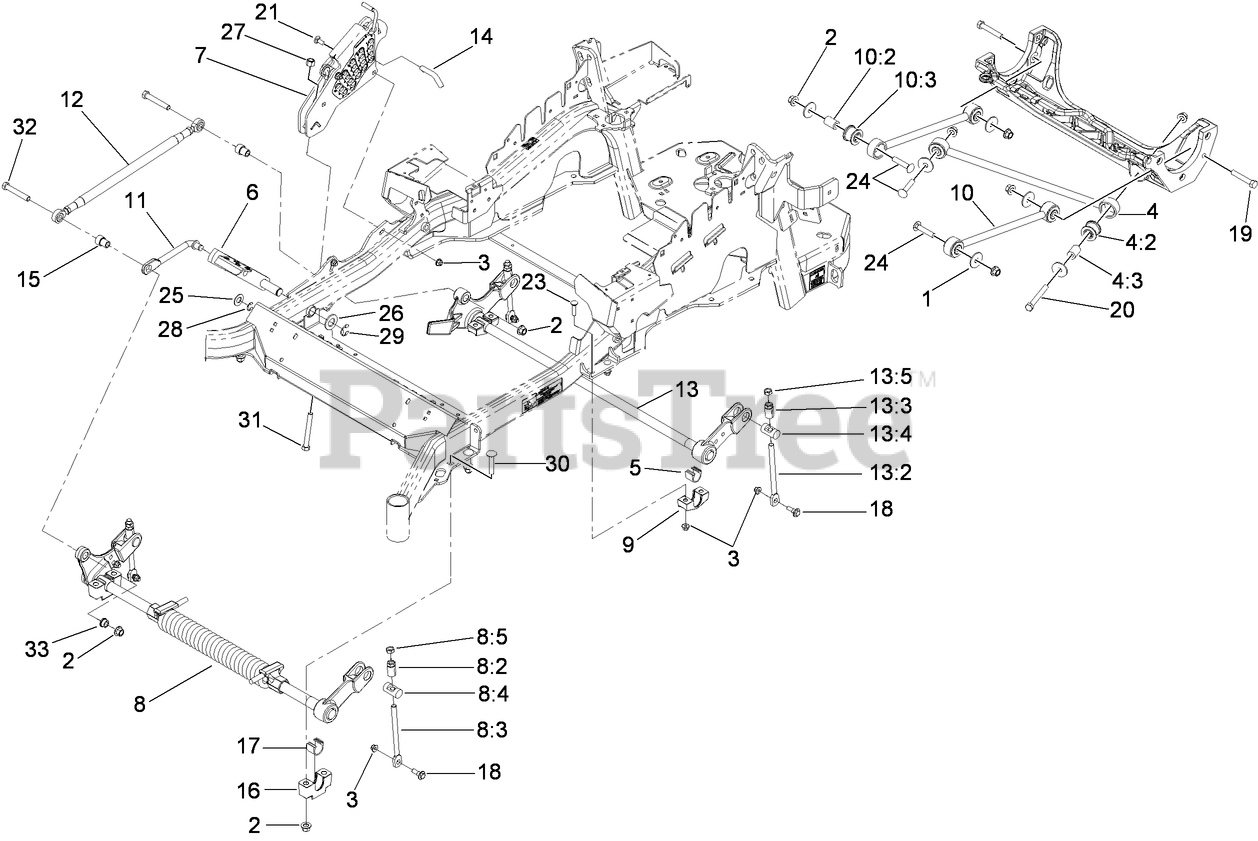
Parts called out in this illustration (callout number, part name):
1	WASHER-THRUST
2	NUT-LOCK
3	NUT-HF, NI
4	PANHARD ROD ASM
4:2	BUSHING-SUSPENSION, RUBBER
4:3	SPACER
5	BEARING-CROSS SHAFT, REAR
6	LEVER-FOOT
7	HOC ASM
8	FRONT CROSS SHAFT ASM
8:2	ADJUSTER-LIFT, DECK
8:3	LINK-ADJUSTER, DECK LIFT
8:4	TRUNNION
8:5	NUT-JAM
9	SUPPORT-CROSS SHAFT, REAR BEARING
10	DECK STRUT ASM
10:2	BUSHING-SUSPENSION, RUBBER
10:3	SPACER
11	LINK-LEVER, FOOT
12	SIDE LINK ASM
13	REAR CROSS SHAFT ASM
13:2	LINK-ADJUSTER, DECK LIFT
13:3	ADJUSTER-LIFT, DECK
13:4	TRUNNION
13:5	NUT-JAM
14	PIN-HOC
15	BUSHING-FLANGE
16	SUPPORT-CROSS SHAFT, BEARING
17	BEARING-CROSS SHAFT, FRONT
18	SCREW-SHOULDER, HHF
19	SCREW-HH
20	SCREW-HH
21	BOLT-CARR
23	SCREW-CARR
24	SCREW-CARR
25	WASHER-FLAT
26	WASHER-FLAT
27	NUT-LOCK, NI
28	E-RING
29	RING-RETAINING, EXT
30	SCREW-CARR, SHORT NECK
31	BOLT-TAP
32	SCREW-HH
33	BUSHING-FLANGE
